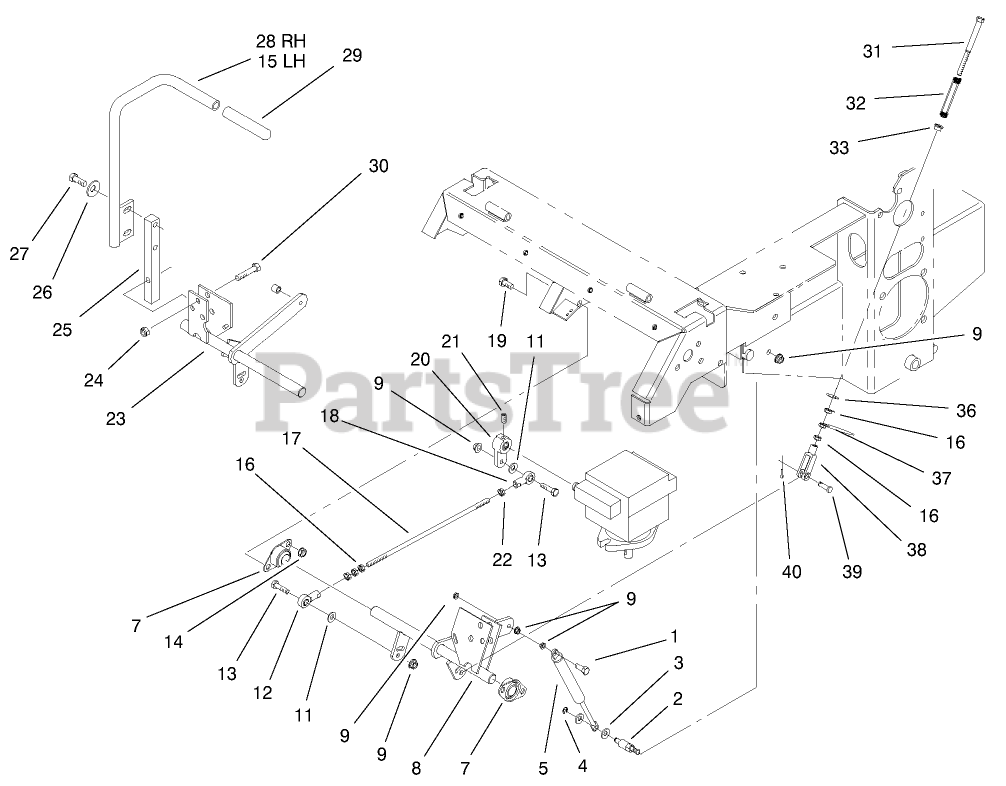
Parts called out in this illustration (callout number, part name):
1	SCREW-HH
2	PIN-DAMPER
3	WASHER-PLAIN
4	RING-RETAINING, EXT
5	DAMPER-CONTROL
7	BEARING-FLANGE, SIDE
8	CONTROL-MOTION, LH
9	NUT-HF
11	WASHER-FLAT
12	BALLJOINT-RH
13	SCREW-HH
14	NUT-HHF, WHIZ
15	LEVER-CONTROL, LH
16	NUT-HEX
17	LINKAGE-PUMP/LEVER
18	BALLJOINT-LH
19	SCREW-HH
20	ARM-CONTROL, PUMP
21	SCREW-SET
23	CONTROL-MOTION, RH
24	NUT-LOCK, NI
25	ARM-CONTROL, SHAFT
26	WASHER-BELLEVILLE
27	SCREW-HH
28	LEVER-CONTROL, RH
29	GRIP-CONTROL, MOTION
30	SCREW-HH
31	BOLT-RETURN, NEUTRAL
32	SPRING-RETURN, NEUTRAL
33	BUSHING-FLANGED
36	WASHER-FLAT
37	NUT-JAM
38	YOKE-ADJUSTABLE
39	PIN-CLEVIS
40	PIN-COTTER
